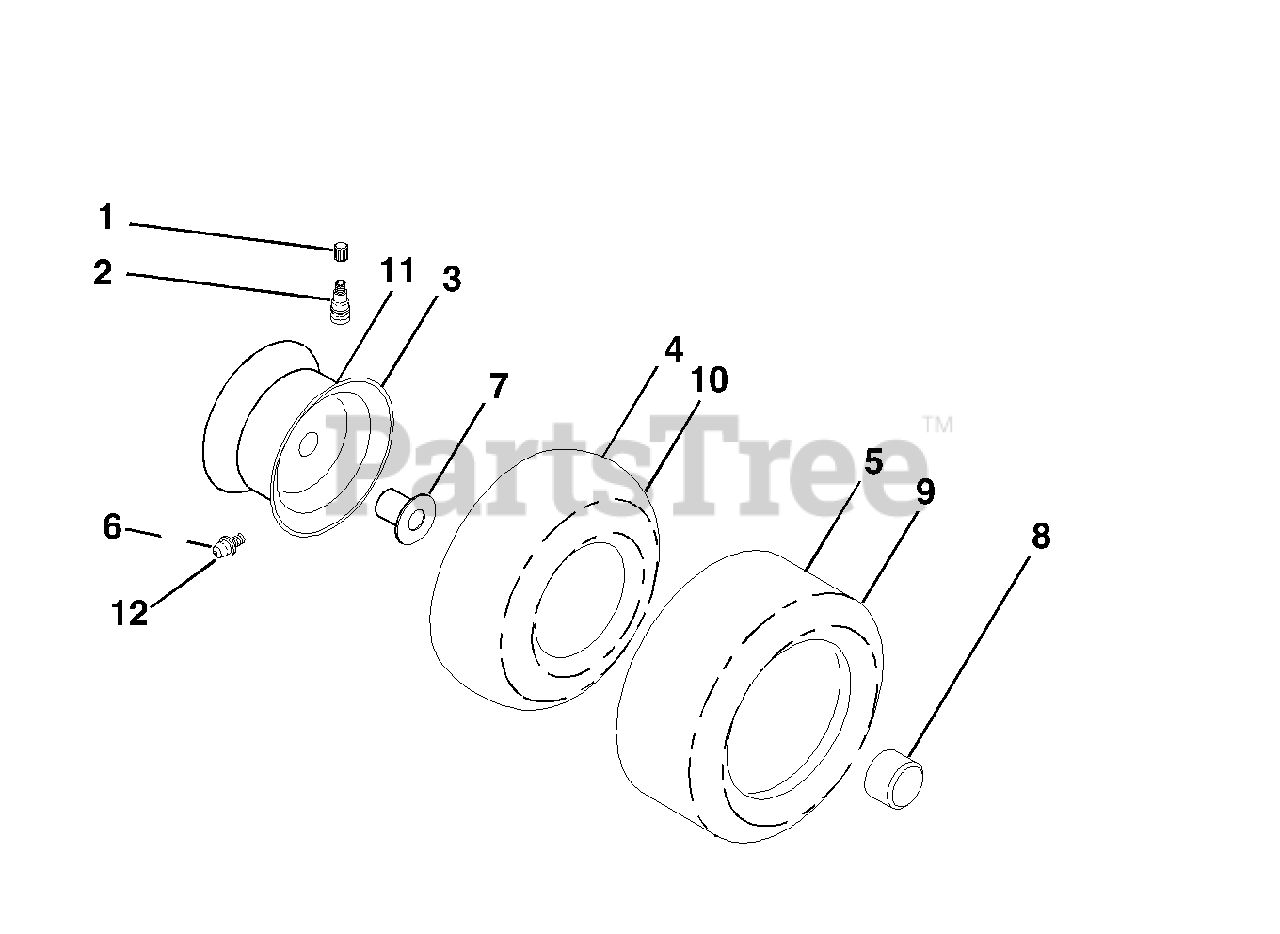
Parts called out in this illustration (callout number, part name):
1	Cap, Valve, Tire
2	Stem, Valve
3	Rim Assembly, Front
4	Tube, Front
5	Tire, Front
6	Fitting, Grease
7	Bearing, Flange
8	Cap, Hub
9	Tire, Rear
10	Tube, Rear
11	Rim Assembly, Rear
12	Fitting, Grease
